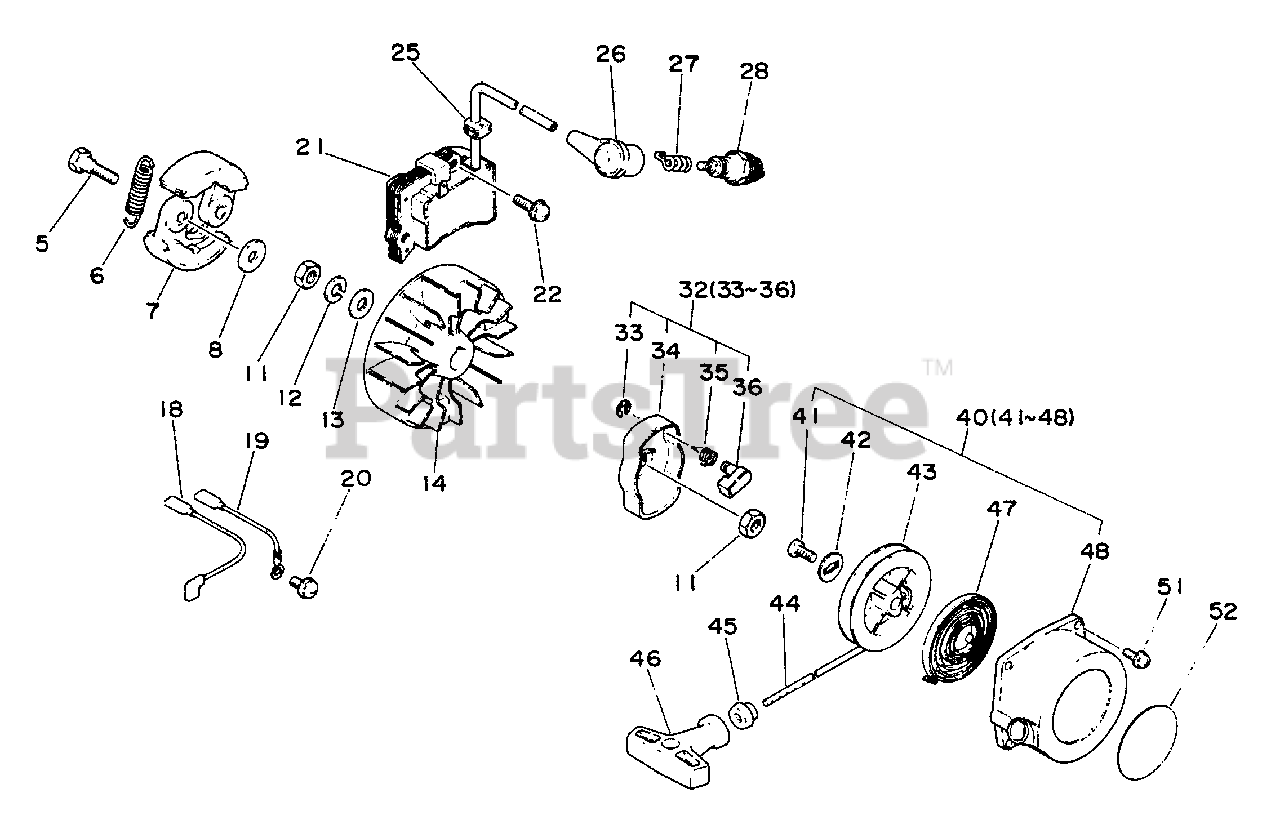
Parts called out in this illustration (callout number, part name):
5	BOLT, CLUTCH
6	SPRING, CLUTCH
7	SHOE, CLUTCH
8	WASHER - 6
12	LOCKWASHER - 8
13	WASHER - 8
14	FLYWHEEL
18	LEAD
19	LEAD - GROUND
20	SCREW - 5X10
21	COIL, IGNITION
22	SCREW - 5X20
26	CAP, SPARK PLUG
27	TERMINAL, SPARK PLUG CAP
28	SPARK PLUG -- CJ-7Y
32	STARTER PAWL ASSY
33	RING, RETAINING - 6
34	CATCHER, PAWL
35	SPRING, RETURN
36	PAWL, STARTER
40	STARTER ASSY
42	WASHER
43	REEL, ROPE
44	ROPE, STARTER - 3.5X850
45	GUIDE, ROPE
46	GRIP, STARTER
47	SPRING, REWIND
48	CASE, STARTER
51	SCREW - 4X14
52	LABEL - ECHO
